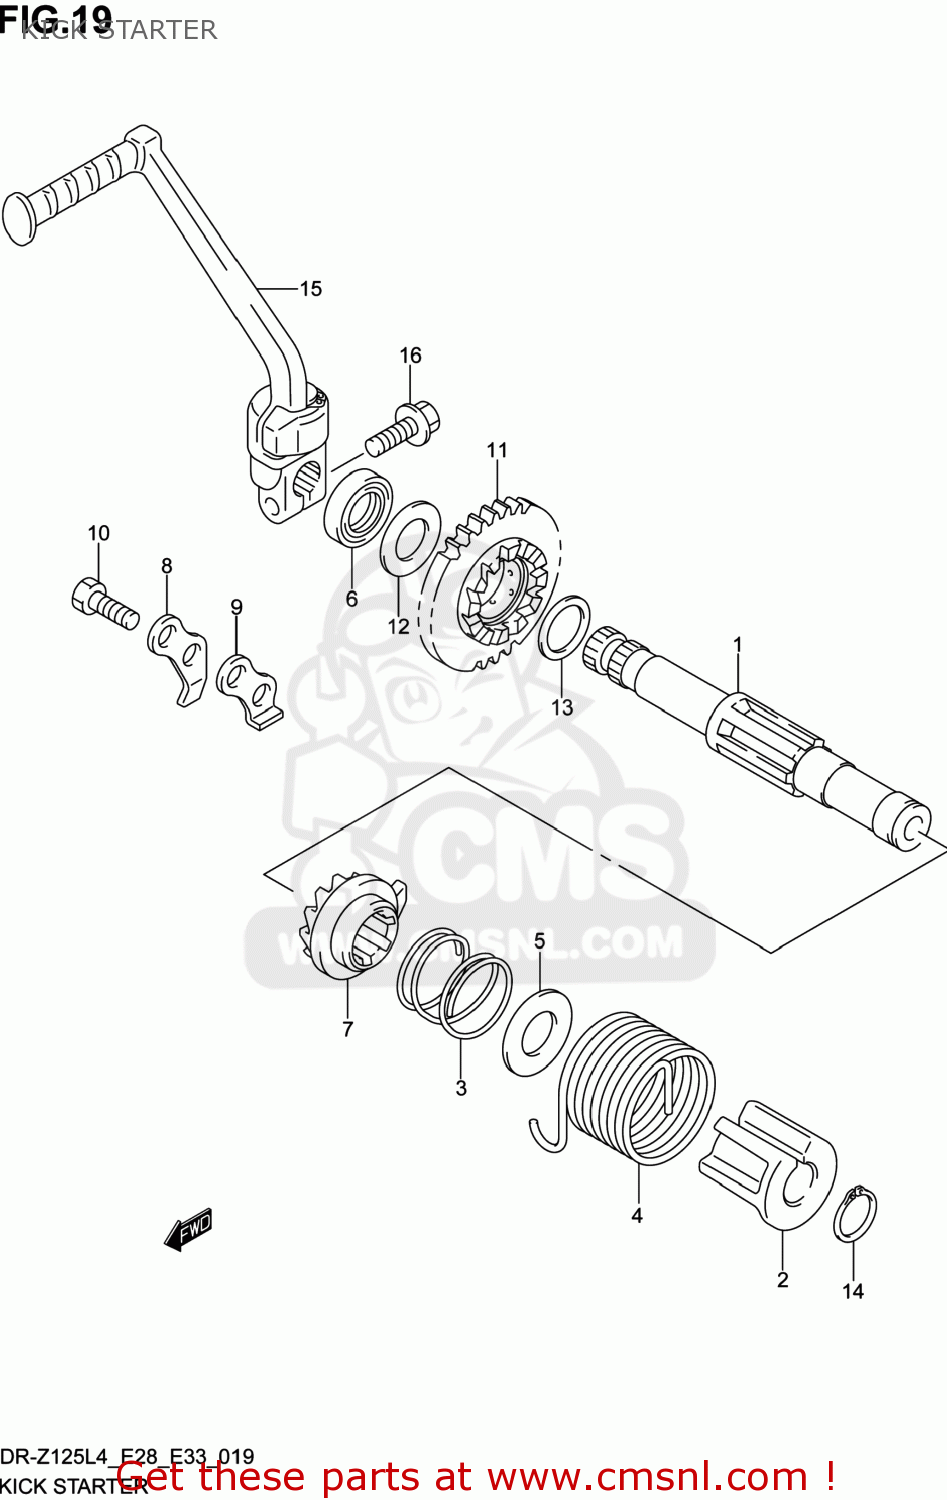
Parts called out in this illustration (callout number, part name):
1	SHAFT,KICK STARTER
2	GUIDE,KICK STARTER SFT SPRING
3	SPRING
4	SPRING
5	WASHER
6	SEAL,OIL(16X24X5)
7	STARTER,KICK
8	GUIDE,KICK STARTER
9	STOPPER,KICK STARTER
10	BOLT(8X20)
11	GEAR,KICK STARTER DRIIVE
12	WASHER(16X30X1)
13	SHIM(20X26X1)
14	CIRCLIP
15	LEVER ASSY,KICK STARTER
16	BOLT
